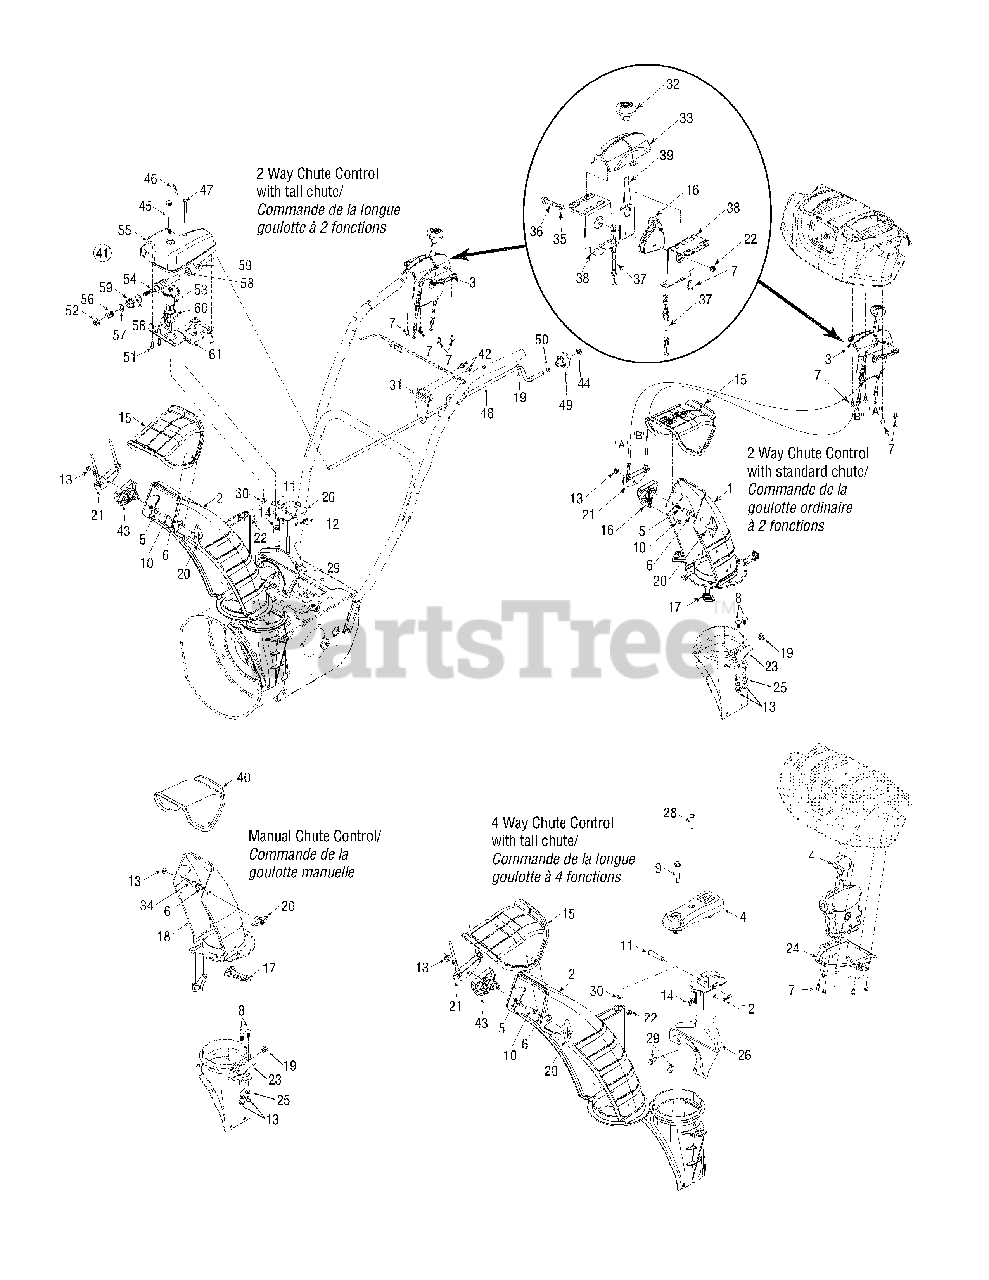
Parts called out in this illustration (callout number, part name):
1	Lower Chute (2 Way)
2	Tall Lower Chute
3	2 Way Chute Control Assembly
4	4 Way Chute Control Assembly
5	Carriage Bolt 5/16-18 x 1.50 Gr. 2
6	Carriage Screw 5/16-18 x 1.0
7	Hi-Lo Screw 1/4-15 x .5
8	Carriage Bolt 5/16-18 x 1.00" Lg
9	Shoulder Screw .312 x 1.7:1/4-20
10	Hex Tapp Scr 1/4 x .75" Lg.
11	Clevis Pin 3/8 x 1.87
12	Bow Tie Cotter Pin
13	Flange Locknut 5/16-18 Gr. F Nylon
14	Wing Nut 1/4-20
15	Upper Chute w/Export Label, Remote
17	Chute Flange Keeper
19	Plastic Bushing .380 ID
20	Handle Knob Assembly
22	Hex L-Flanged Nut 1/4-20 Gr. F Nylon
25	Flat Washer .349 ID x .879 OD x .063
27	Hi-Lo Screw 1/4-15 x .50
28	Hex Hd. Cap Screw 1/4-20 x 1.5 Gr. 5
29	Hex Hd. Cap Screw 5/16-24 x .75
30	Flat Washer .25 ID x .63 OD x .0515
33	Control Cover - 2 Way
34	Carriage Bolt 5/16-18 x .75
35	Spring Washer .390 x .625 x .012
36	Flg Shlder Screw .310 x .995: 1/4-20
37	Cable - w/standard chute
37	Cable - w/tall chute
41	Gearbox Assembly
42	Hex Wash Hd TT Scr. 1/4-20 x .625
44	Push Nut 3/8" Rod
45	Flg. Shoulder Screw .312 x 3.5: 1/4-20
46	Internal Cotter Pin
47	Hex. Hd. Cap Scr. 1/4-20 x 3.0 Gr. 5
50	Flat Washer .385 x .62 x .063
51	Hi-Lo Screw #12-16 x .75
52	Hex L-Flanged Nut 3/8-16 Gr. F Nylon
53	Gear 23 teeth helical w/hub
54	Worm Shaft
56	Compression Spring .39 x .60 x .88
57	Flat Washer .385 x .87 x .06
58	Flat Washer .625 x 1.0 x .067
59	Hex Flg. Bearing
